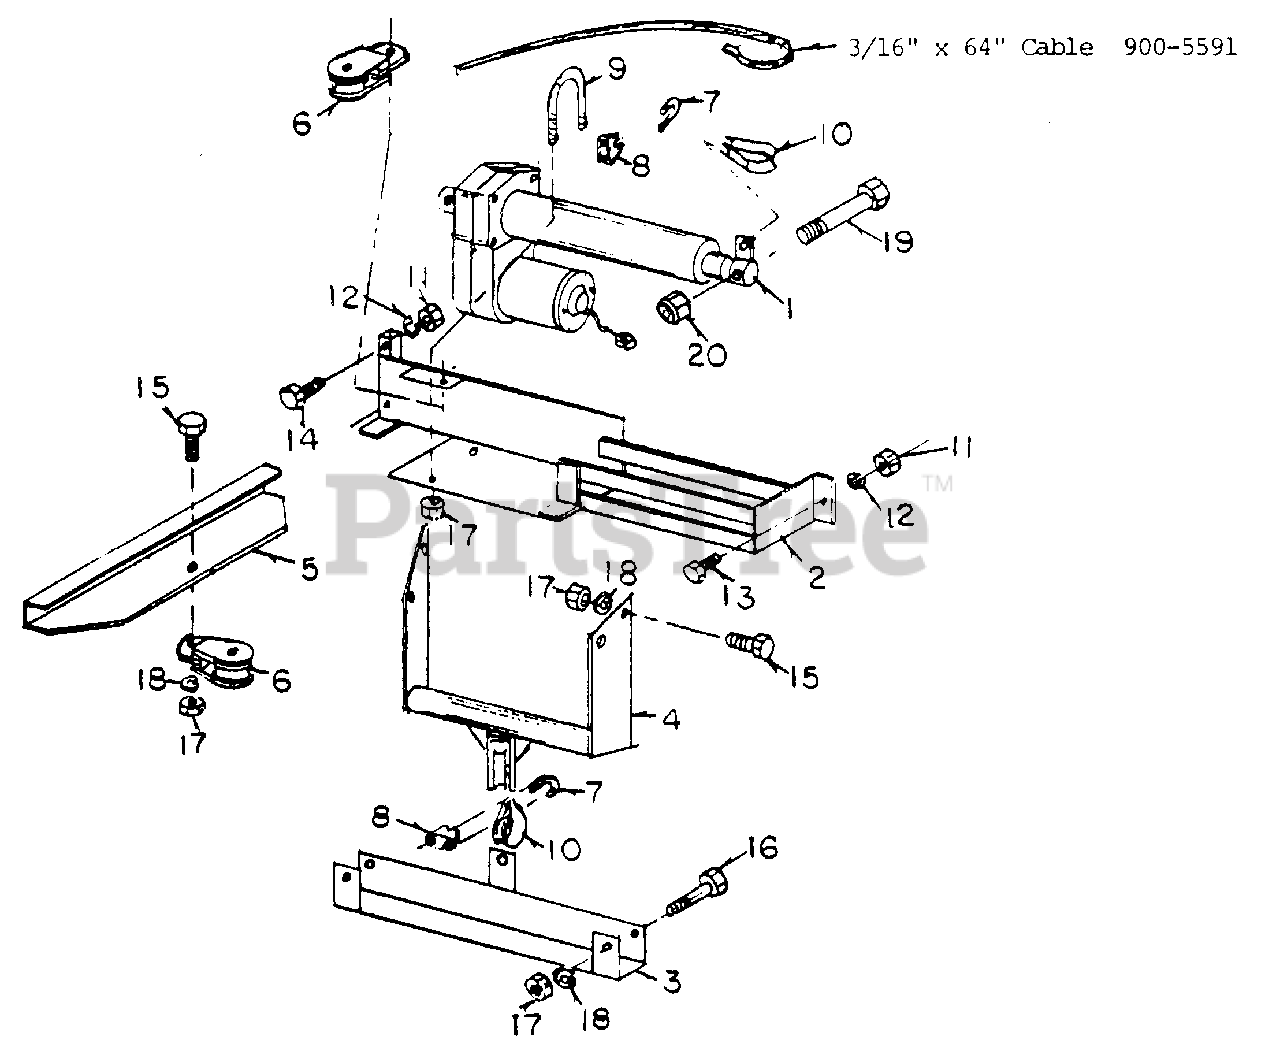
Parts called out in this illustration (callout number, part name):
1	Actuator
2	Actuator Mount
3	Deck Lift Adapter
4	Cable Mount
5	Cable Mount
7	U-Bolt
9	U-Bolt
11	3/4-20 Nuts
12	3/4 Lock Washer
13	1/4-20 x 3/4
14	1/4-20
15	5/16-18 x 1
16	5/16-18 x 2
17	5/16-18 Nut
18	5/16 Lock Wasner
19	1/2-13 x 4
20	1/2-13 Lock Nut
